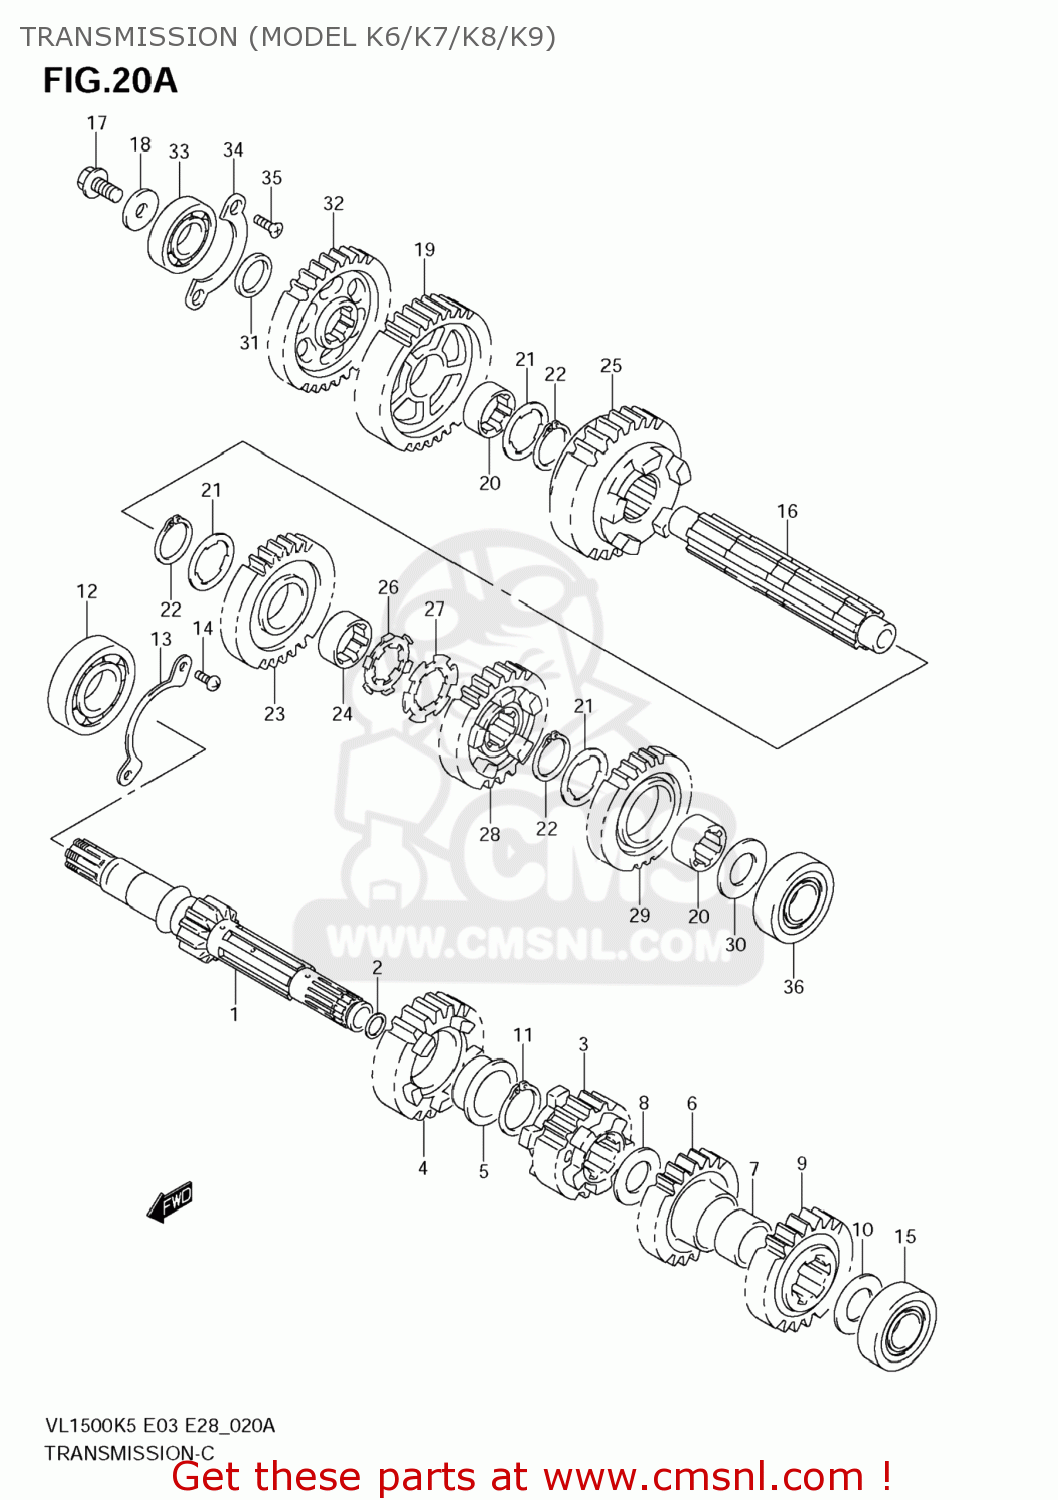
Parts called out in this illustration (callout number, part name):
1	SHAFT,COUNTER(NT:12)
2	O RING(D:1.9,ID:16.6)
3	GEAR,2ND DRIVE(NT:17)
4	GEAR,3RD DRIVE(NT:21)
5	BUSH(28X32X2)
6	GEAR,4TH DRIVE
7	BUSH,4TH DRIVE GEAR
8	SHIM(22X32X1)
9	GEAR,5TH DRIVE(NT:26)
10	SHIM(20X32X1)
11	CIRCLIP
12	BEARING(25X62X17)
13	RETAINER,CNTR SHAFT BEARING
14	SCREW
15	BEARING(20X52X15)
16	SHAFT,DRIVE
17	BOLT(10X24)
18	WASHER
19	GEAR,1ST DRIVEN(NT:36)
20	BUSH
21	WASHER,LOCK
22	CIRCLIP
23	GEAR,2ND DRIVEN(NT:31)
24	BUSH,3RD DRIVEN GEAR
25	GEAR,3RD DRIVEN(NT:28)
26	WASHER
27	WASHER,LOCK
28	GEAR,4TH DRIVEN(NT:25)
29	GEAR,5TH DRIVEN(NT:23)
30	WASHER
31	WASHER(22X32X3)
32	GEAR,OVER DRIVING DRIVE(NT:34)
33	BEARING(22X56X16)
34	RETAINER,CNTR SHAFT BEARING
35	SCREW(6X12)
36	BEARING(20X52X15)
